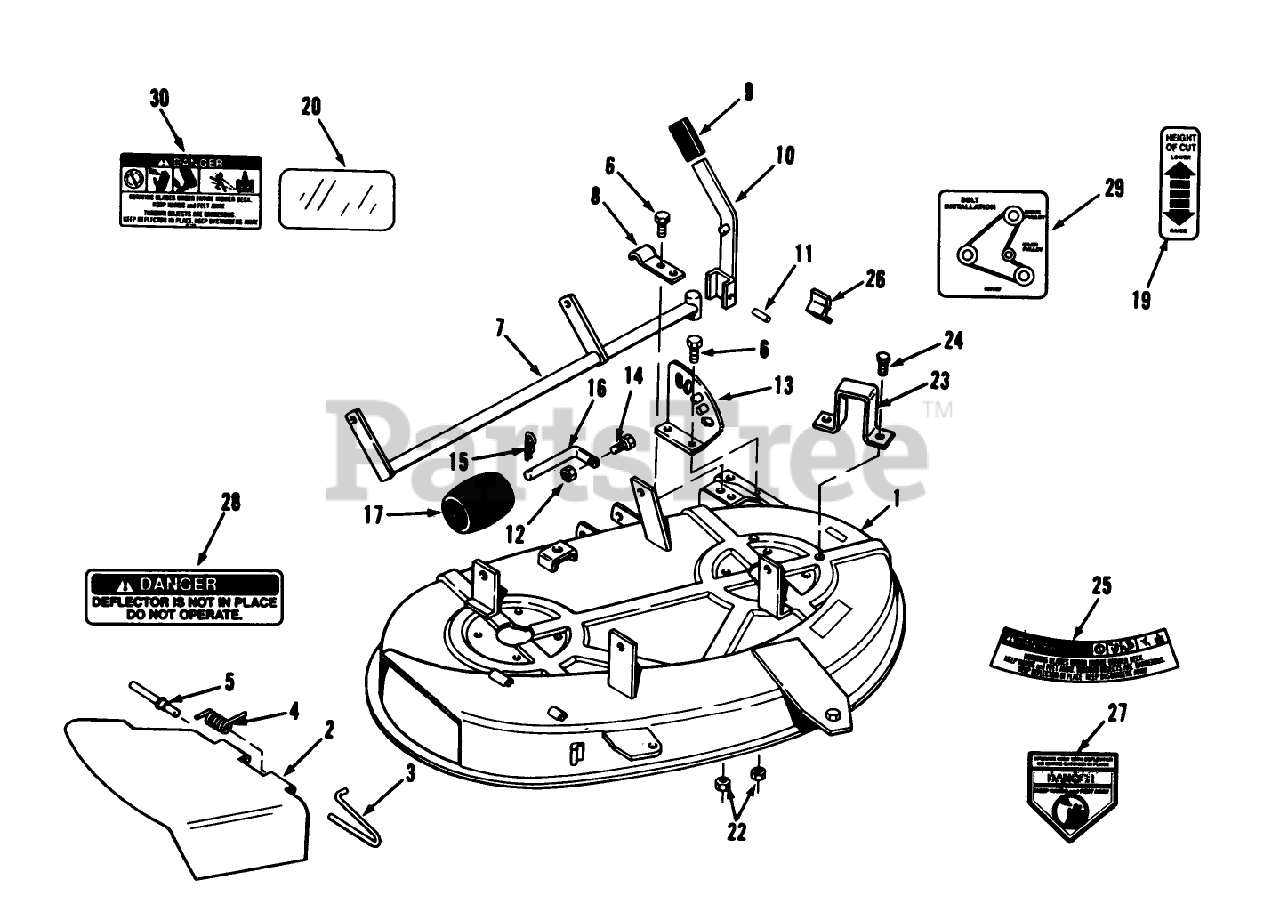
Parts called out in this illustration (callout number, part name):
2	Chute-Discharge
3	ROD-HINGE FRONT
4	SPRING-TORSION
5	ROD-HINGE REAR
6	Bolt
10	Lever-Mower L.H.
11	SPIROL PIN 3/8X1 1/2
17	ROLLER
19	DECAL-HOC
20	DECAL-OVERLAY
25	DECAL - DANGER
26	CLIP-SPRING
28	DECAL-DANGER
30	DECAL-DANGER, THROWN OBJECT
